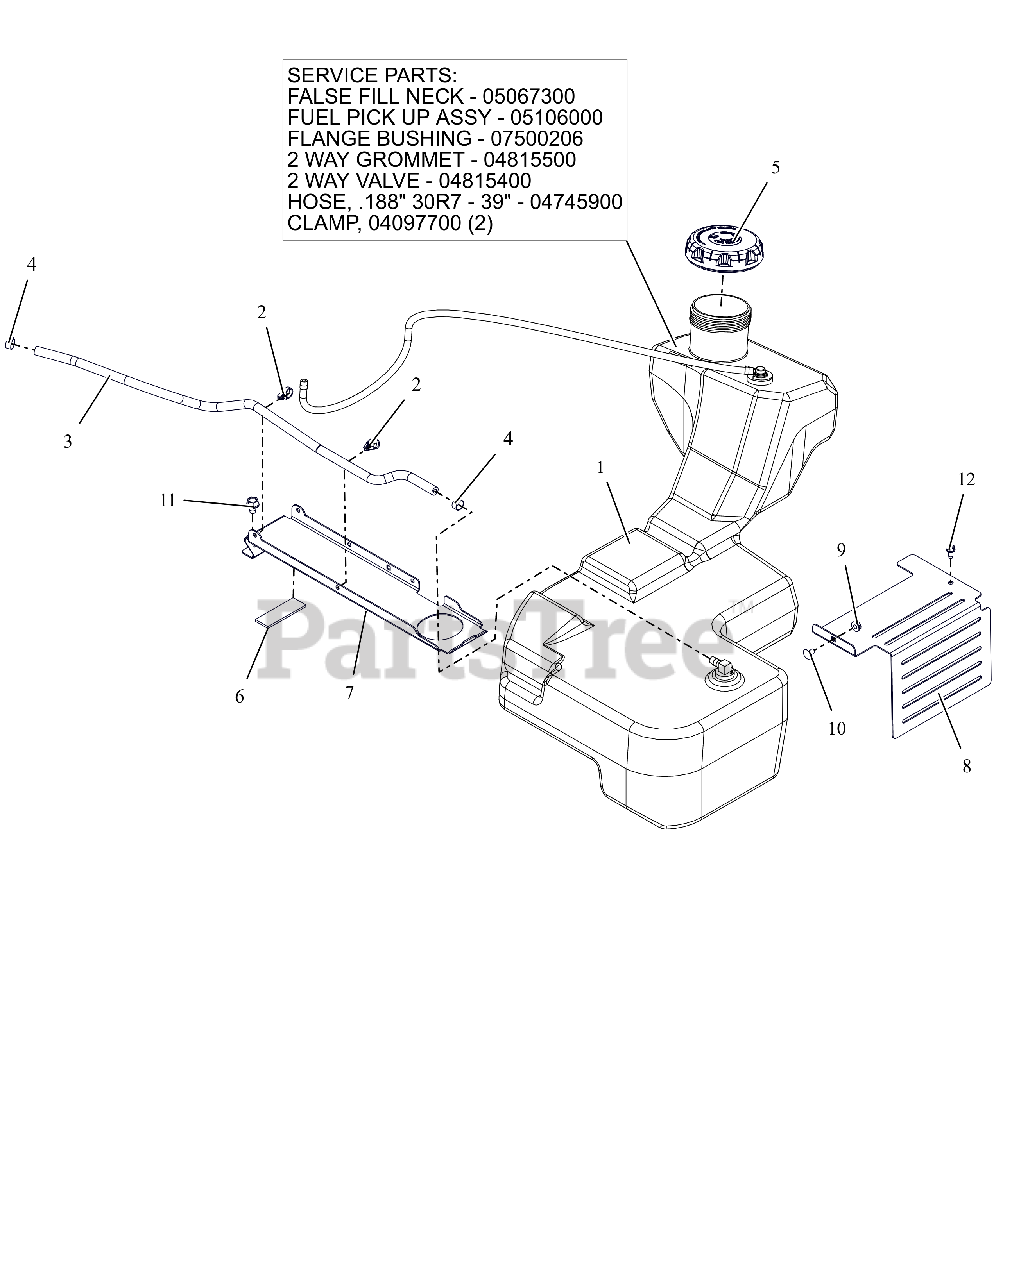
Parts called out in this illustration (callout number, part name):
1	ASM, HD FUEL TANK
1	ASM, HD FUEL PICK-UP
1	BSHG-FLG .375X1.062X.625 NITR
1	GROMMET, 2-WAY
1	VALVE, 2-WAY
1	HOSE, .188 30R7 BULK
1	CLAMP-HOSE, SPRING .188
2	ROUTING CLIP (1/2" ID)
3	HOSE, .25 LOW-PERM BULK GAS
4	CLAMP, FUEL LINE
5	CAP, FUEL VENTIN AUTOLOCK
6	PAD,RBR 1.0"X3.0" W/ADHESIVE
7	BRKT, FUEL TANK HOLD DOWN
8	GUARD, TRANSAXLE FAN LH (BLACK)
9	NUT-LK-CTR-FLG .25-20 ZC120
10	BLT, RHSSN.25-20X.500 G5 ZCC
11	SCR,TAP .375-16X.50 HWH TR ZCC
12	SCR-TAP .25-20X.50 HWH ZCC
